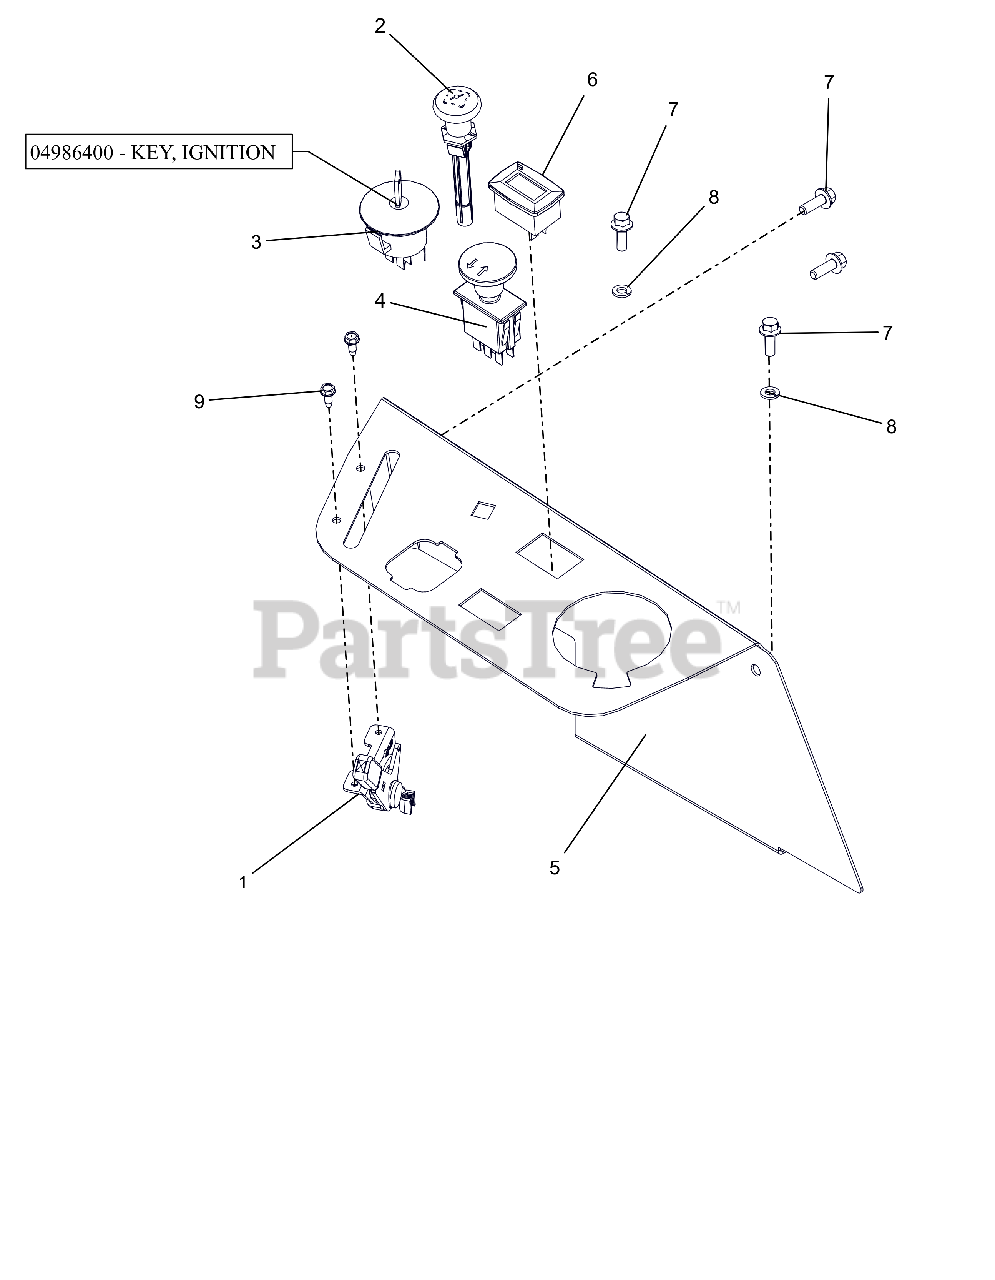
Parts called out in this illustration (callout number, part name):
1	CABLE - THROTTLE CONTROL
2	CABLE - CHOKE, SNAP-IN
3	KEYSWITCH-IGNITION 4 POS
3	KEY, IGNITION
4	SWITCH, CLUTCH (YELLOW)
5	PANEL, RIGHT SIDE FENDER MOUNT
6	METER, HOUR W/MAINTENANCE
7	BLT,HEX-FLG .25-20X.75 G5 BFP
8	@WSHR-LK .25X.062 REG YWZC
9	@SCR-TAP 10-24X.50 HWH TR YWZC
